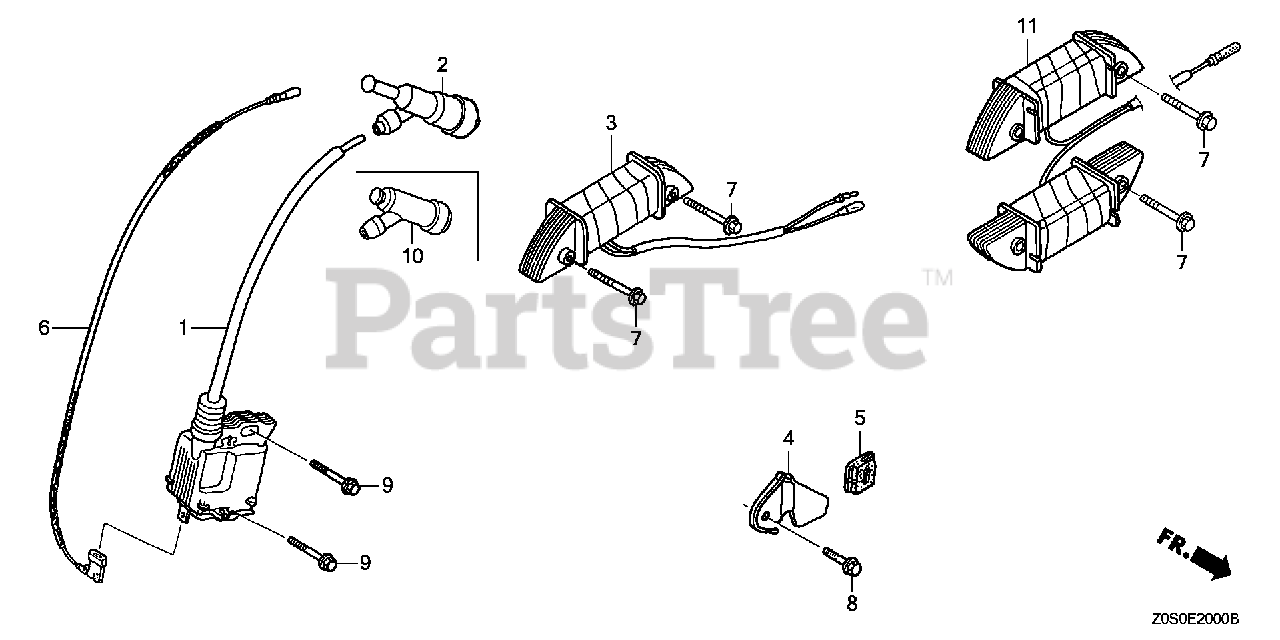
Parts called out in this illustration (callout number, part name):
1	COIL ASSY., IGNITION (TEC)
2	CAP ASSY., NOISE SUPPRESSOR (TEC)
3	COIL ASSY., LAMP (12V/25W)
4	CLAMP, WIRE
5	GROMMET, WIRE
6	WIRE, STOP SWITCH (370MM)
7	BOLT, FLANGE (6X28) (CT200) Use up to Engine SN 1530314.
8	BOLT, FLANGE (5X10)
9	BOLT, FLANGE (6X25) Use up to Engine SN 2056819.
